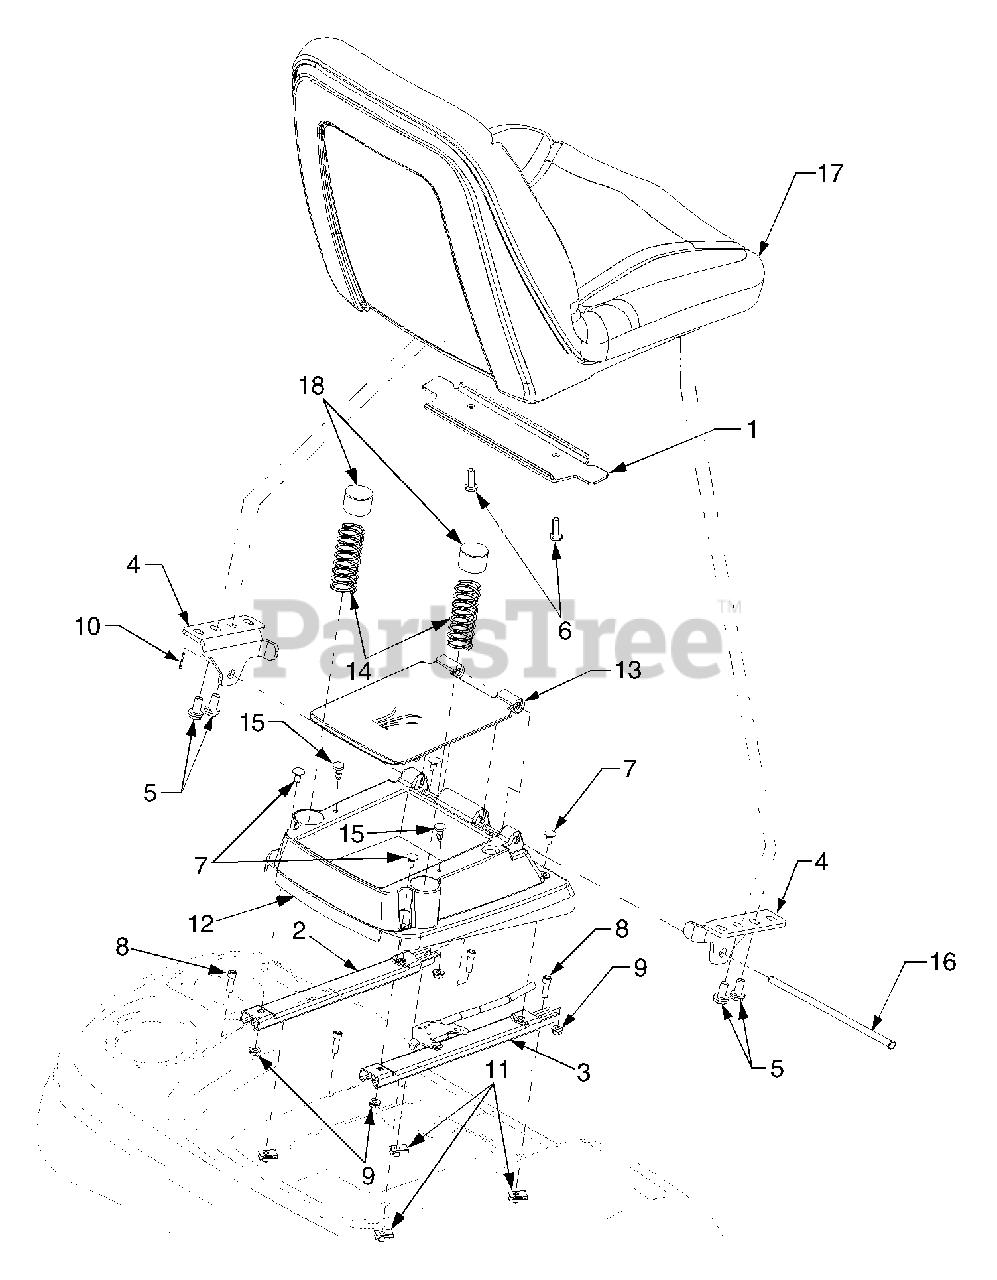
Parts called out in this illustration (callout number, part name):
1	Bracket, Seat Spring Support
2	Track, Seat, w/o Latch
3	Track, Seat, w/Latch
6	Screw, Phil Pan Hd. Mach 5/16-18 x 1.0
7	Carriage Bolt, 5/16-1 8 x .62
8	Screw, Pan Torx Hd. 5/16-18 x 1.0
9	Nut, Hex Flange Lock, 5/16-18
10	Pin , Cotter, 3/32 x .7 5
11	Speed Nut, U-Type, 5/16-18
12	Base, Seat
13	Lid, Tlbx
14	Spring, Compression
15	Bumper
16	Rod, Seat Pivot
17	Seat, High Back
18	Cap, Spring
